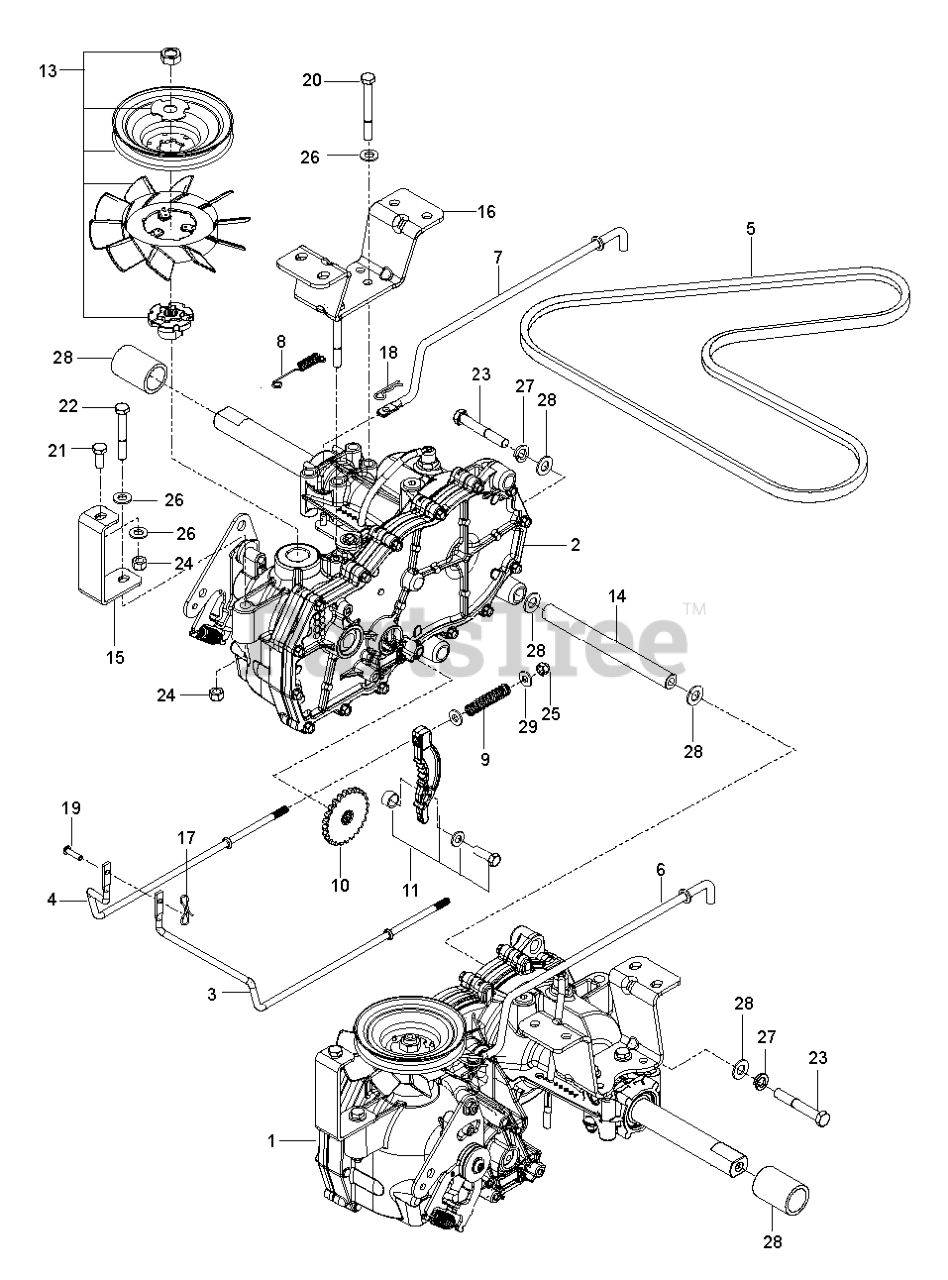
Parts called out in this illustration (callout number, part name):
1	TRANSMISSION EZT; DD; LONG; LE
2	TRANSMISSION EZT; DD; LONG; RI
3	LINKAGE.BRAKE.LT
4	LINKAGE, BRAKE RT
5	BELT, HYDRO PUMP
6	ROD.BYPASS.RZ.LH
7	ROD.BYPASS.RHT
8	SPRING.ROD.BYPASS.EZT
10	HG_DISC COG BRAKE 51635
11	HG_KIT BRAKE ARM (EZT)
13	KIT FAN/PULLEY 72137
14	SPACER TUBE EZT
15	SUPPORT.FRONT.TRANS.PNTX431
16	BRACKET.EZT.MOUNT.REAR.PNTX431
17	PIN COTTER;LOCKING;BOWTIE;1IN
18	HAIRPIN #2
19	PIN.CLEVIS.3/16X.475
21	HCS 5/16C X 3/4
22	BOLT.FIN HEX 5/16-18UNC X2 1/4
23	HCS 3/8C X 2 1/2
24	NUT.71038.31-18.HEX.NYLOCK
25	NUT.1/4-20.HEX.NYLOC.ZD
26	WASHER
27	SLW 3/8 STD
28	WASHER
